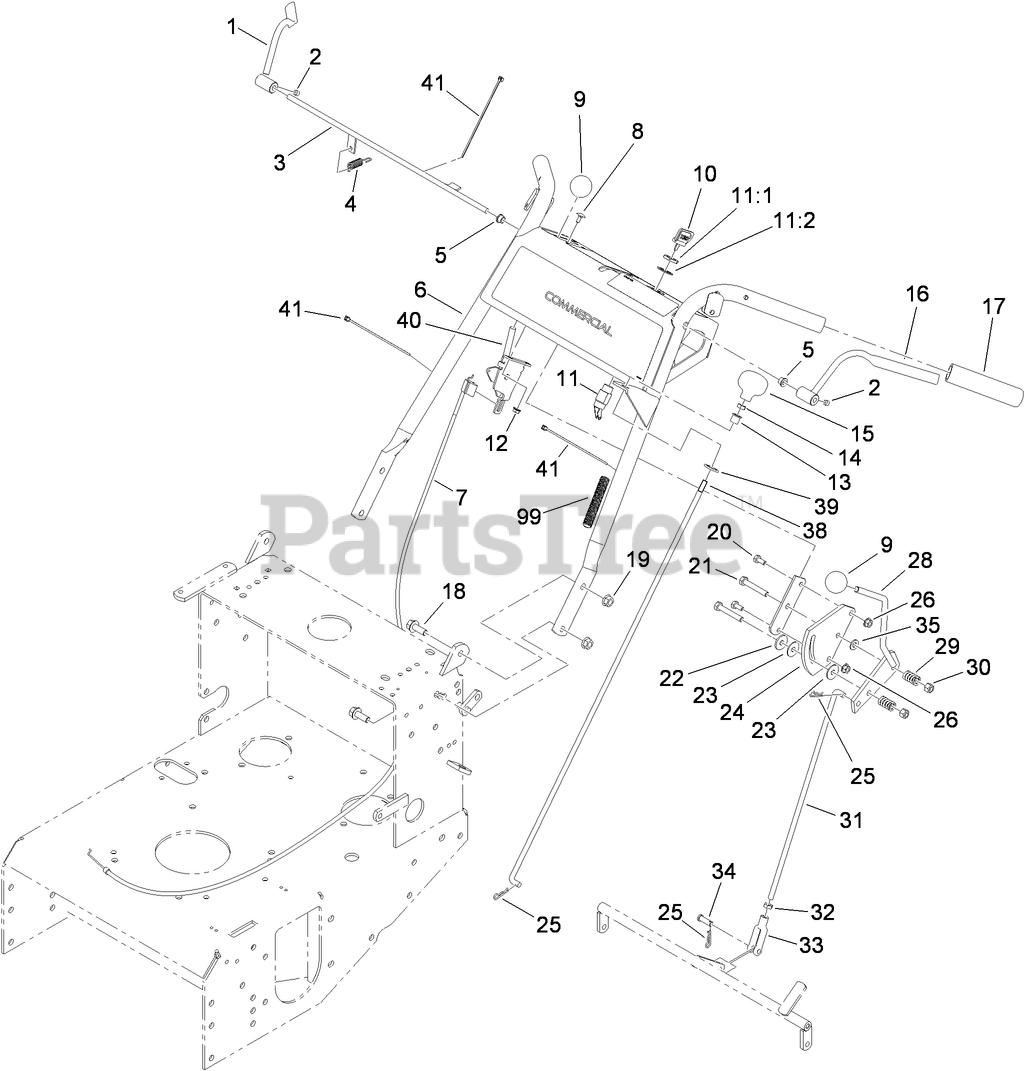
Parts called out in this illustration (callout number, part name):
1	RH OPERATOR PRESENCE CONTROL LEVER ASM
2	SCREW-SET
3	ROD-CONTROL, OPERATOR PRESENCE
4	SPRING-EXTENSION
5	BUSHING-NYLON
6	HANDLE ASM
7	CABLE-CONTROL, THROTTLE
8	BOLT-CARR
9	KNOB-BALL
10	KEY-IGNITION
11	SWITCH-ON / OFF
11:1	NUT-HH
11:2	WASHER-TOOTH, INTERNAL
12	NUT-LOCK, FLANGE
13	Bearing-Nylon
14	NUT-JAM
15	Knob-Push / Pull
16	LH OPERATOR PRESENCE CONTROL LEVER ASM
17	GRIP-FOAM
18	SCREW-HHF
19	NUT-HF
20	SCREW-HH
21	SCREW-HH
22	Washer-Friction
23	Washer-Friction
24	PLATE-LEVER, SHIFTER
25	PIN-COTTER
26	NUT-HF
28	LEVER-SHIFT
29	SPRING-COMPRESSION
30	NUT-LOCK, NI
31	Rod-Control, Speed
32	NUT-JAM
33	YOKE-ADJUSTABLE
34	PIN-CLEVIS
35	WASHER-PLAIN
38	Linkage-Blade
39	NUT-PUSH
40	LEVER-CONTROL
41	TIE-CABLE
99	HARNESS-WIRING
